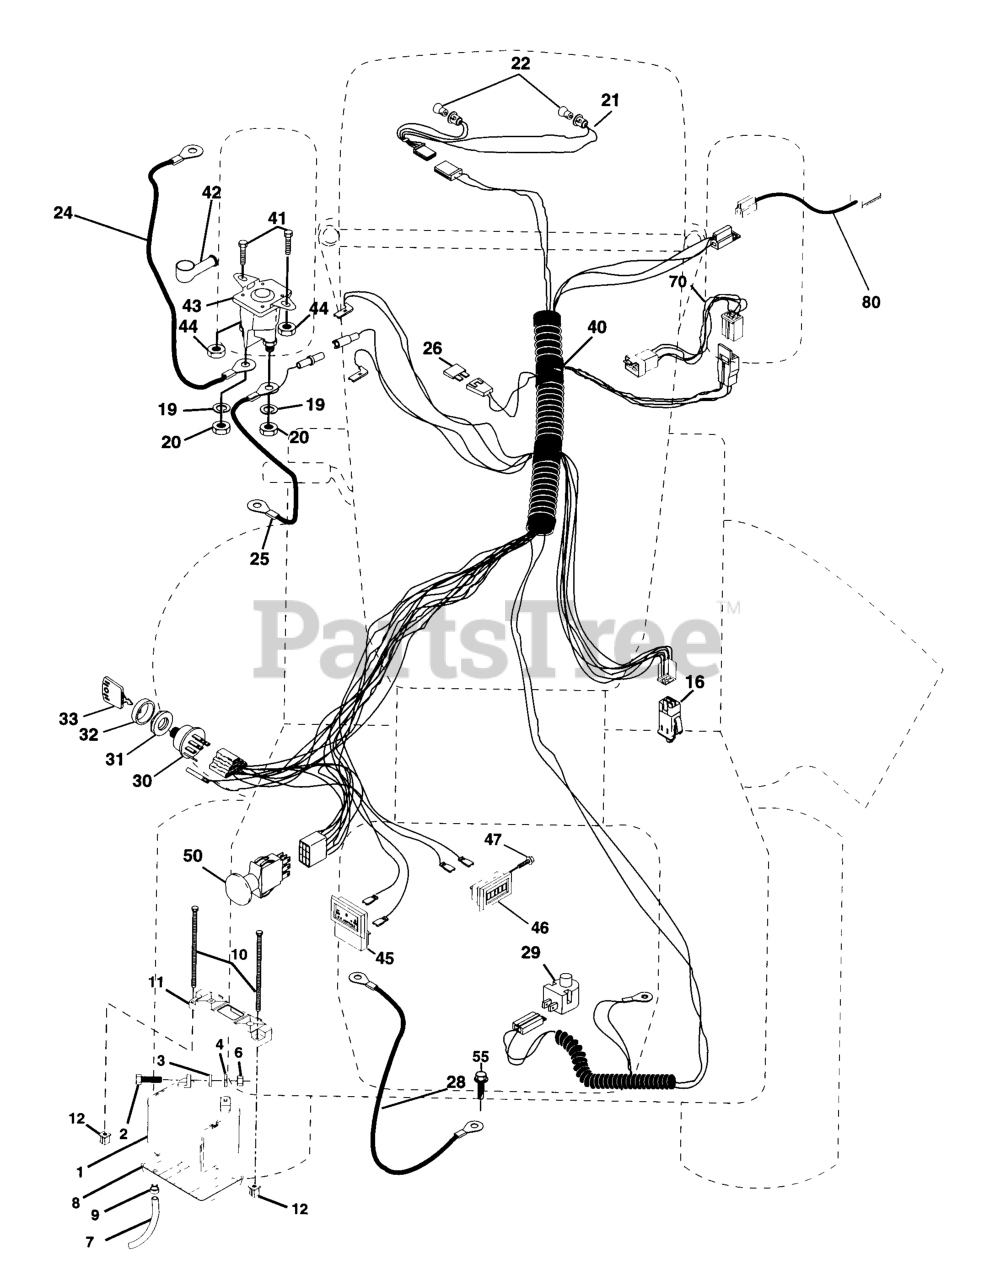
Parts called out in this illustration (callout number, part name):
1	BATTERY
2	BOLT.HEX.1/4.X.3/4.DICHROMATE
3	WASHER
4	LOCKWASHER
6	NUT
7	PLASTIC TUBE
8	BATTERY TRAY T
9	HOSE CLAMP T
10	BOLT 1/4-20 X 7.5
11	BATTERY HOLDDOWN FRONT MOUNT
12	NUT, PUSH NYLON 1/4" BATTERY
16	SWITCH INTERLOCK
19	LOCKWASHER
20	NUT
21	HARNESS LIGHT SOCKET
24	BATTERY CABLE GT
25	CABLE BATTERY 6 GA 22" W/16W
28	CABLE GROUND 6 GA 21" 90T BLK
29	RP.SWITCH.PLUNGER.NC.GRAY
30	SWITCH.IGNITION.4.POSITION
31	NUT IGNITION
32	COVER SWITCH KEY
33	KEY.MOLDED.GENERIC
40	IGN HARNESS
41	BOLT
42	TERMINAL COVER
43	SOLINOID
44	Nut Keps Hex 1/4-20 Unc
45	AMMETER
46	HOUR METER T
47	Screw 10-24 x 1/2 Black
50	SWITCH PTO 3 PDT
55	Screw Thdrol 5/16-18 x 1/2 Tyt
70	HARNESS ENG. KOHLER
80	HARNESS, CLUTCH
